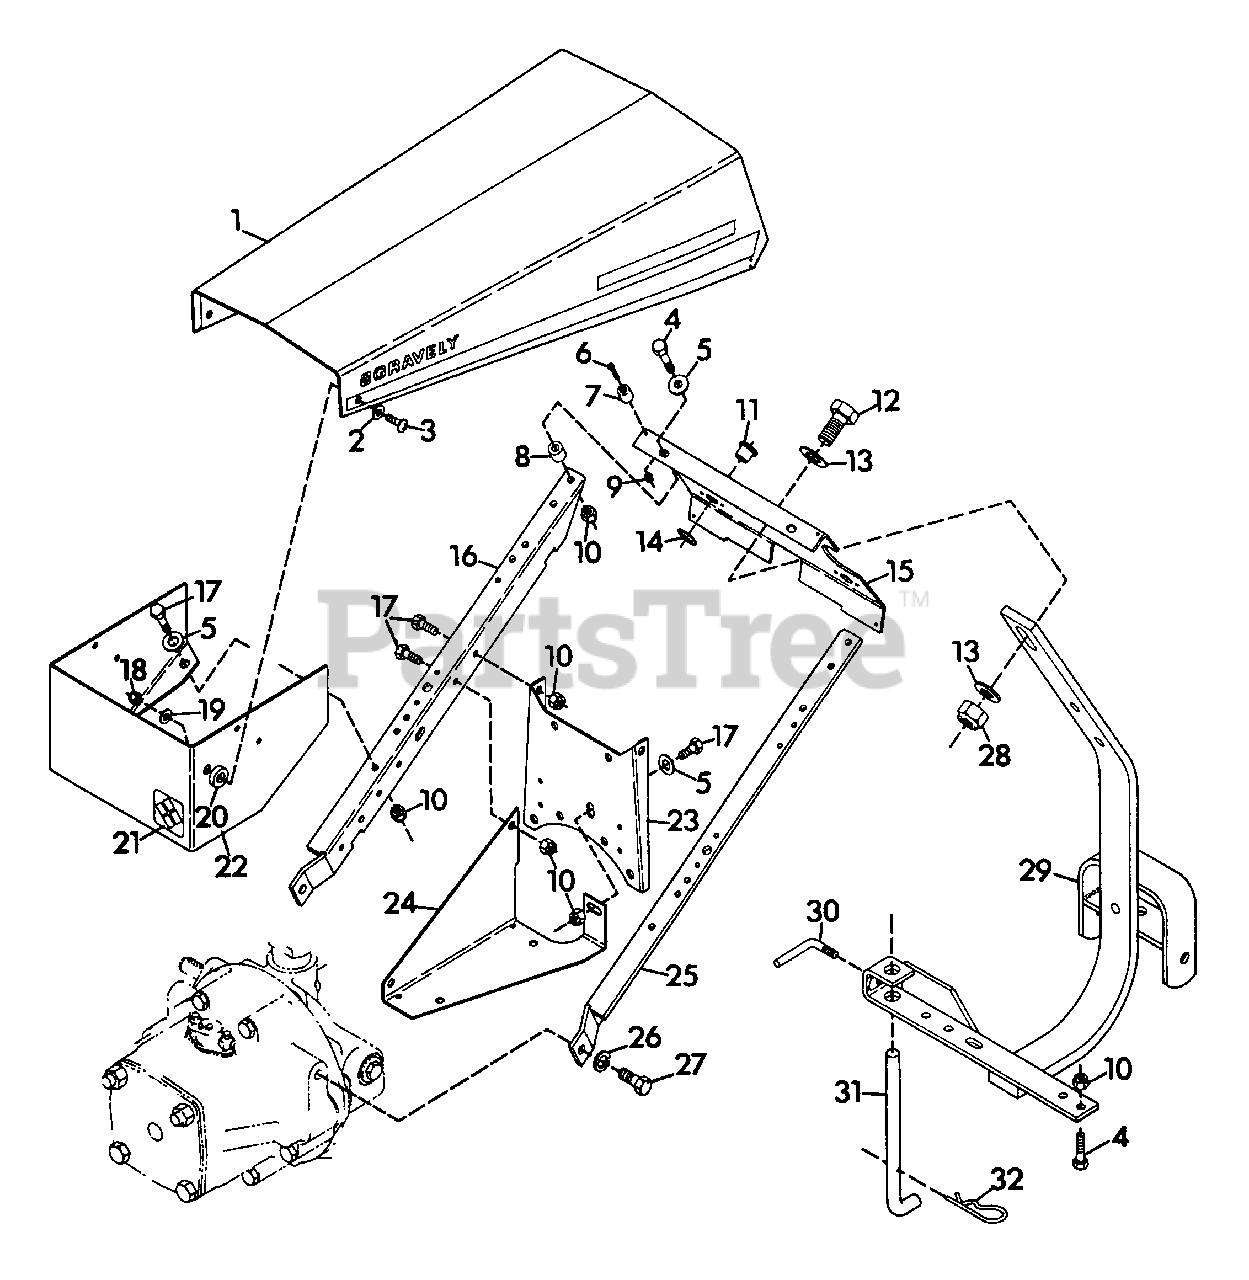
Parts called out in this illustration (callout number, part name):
1	Assembly, Hood
2	Washer, Flat .281 x .625 x .065
3	Screw, Machine 1/4-20 x 1.00
4	Bolt, Hex 3/8-16 x 1.50
5	Washer, Flat .406 x .812 x .065 (Manual Start)
5	Washer, Flat .406 x .812 x .065 (Electric Start)
6	Screw, Machine 6-32 x .625
7	Bumper
8	Bushing, Reverse Idler
9	Nut, Machine Lock 6-32
10	Nut, Lock 3/8-16 (Manual Start)
10	Nut, Lock 3/8-16 (Electric Start)
11	Bushing .513 x .750 x .625
12	Bolt, Hex 5/8-11 x 2.00
13	Washer, Flat .656 x 1.250 x .100
14	Ring, Retaining
15	Plate, Silk Screen (Manual Start)
15	Plate, Silk Screen (Electric Start)
16	Support, Handlebar R. H.
17	Bolt, Hex 3/8-16 x .875 (Manual Start)
17	Bolt, Hex 3/8-16 x .875 (Electric Start)
18	Nut, Lock 1/4-20
19	Washer, Flat .313 x .875 x .065
20	Bushing, Hood
21	Decal
22	Support, Hood
23	Bracket
24	Tray, Battery (Electric Start)
25	Support, Handlebar L. H.
26	Washer, Lock 1/2 Reg.
27	Bolt, Hex 1/2-13 x 1.00
28	Nut, Lock 5/8-11
29	Weldment, Hitch 8 H.P.
30	Handle, Adjusting
31	Stand, Kick
32	Pin, Hair
